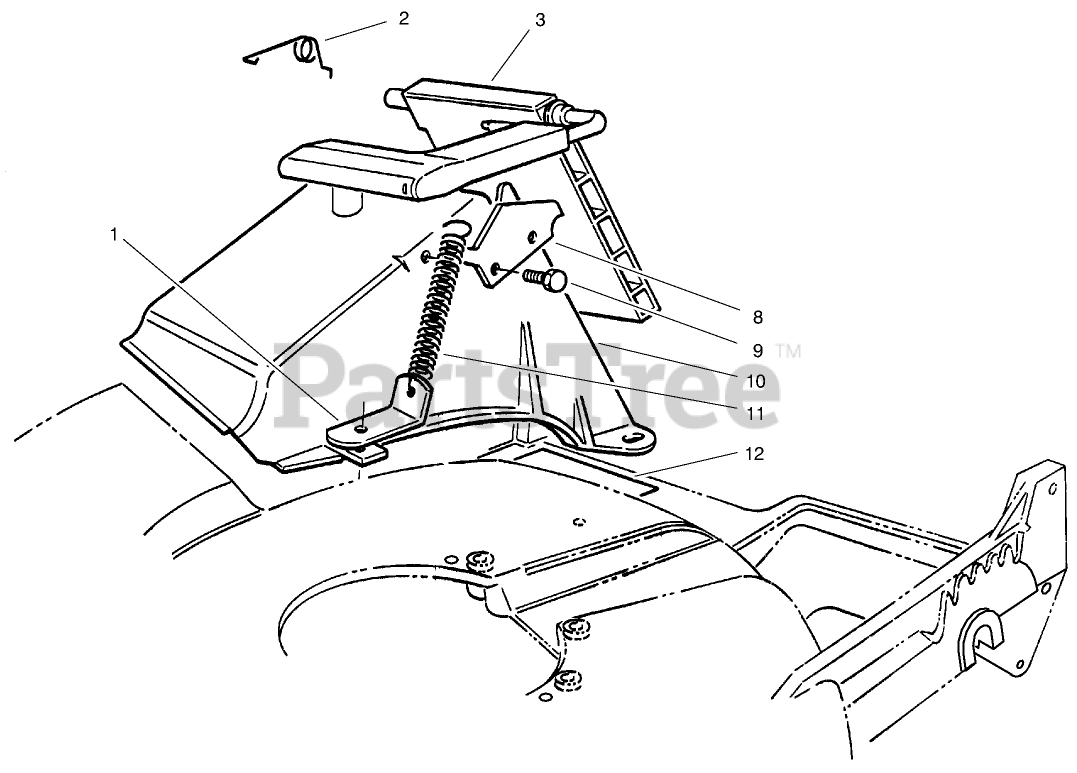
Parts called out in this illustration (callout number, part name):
1	BRACKET-SPRING
2	RETAINER-DOOR
3	DISCHARGE DOOR ASM
8	LATCH-PLATE
9	SCREW-PLASTITE
10	TUNNEL-DISCHARGE
11	SPRING-DOOR
12	DECAL - CAUTION
